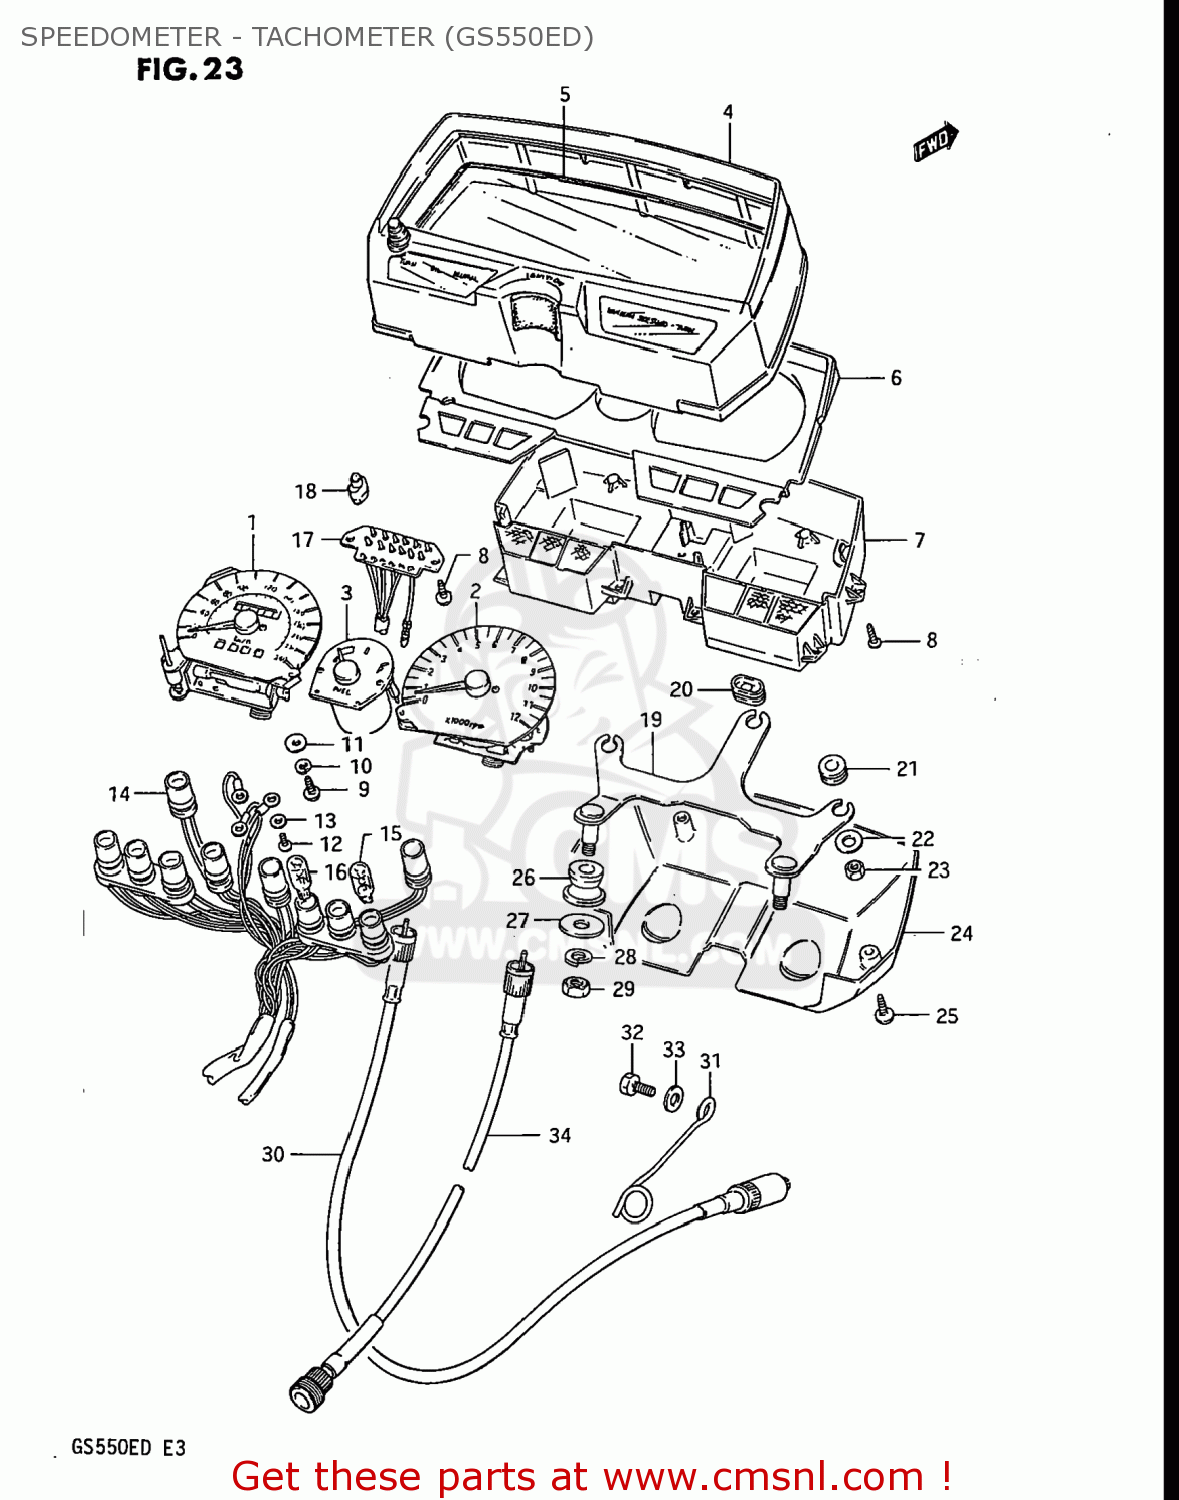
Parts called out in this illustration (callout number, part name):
1	SPEEDOMETER
2	TACHOMETER
3	METER,FUEL
4	HOOD,METER
5	GLASS,SPEEDOMETER
6	PLATE,METER WINDOW
7	CASE,METER,INNER
8	SCREW,GEAR INDICATOR
9	SCREW
10	LOCK WASHER
11	WASHER
12	SCREW
13	WASHER
14	SOCKET
15	BULB(12V3.4W,T10,BF175-01450A)
16	BULB(12V1.7W,T10,WB121)
17	SOCKET,GEAR INDICATOR
18	BULB(14V1.12W)
19	BRACKET,METER
20	CUSHION,METER
21	CUSHION,METER
22	WASHER,METER
23	NUT
24	COVER,METER,UNDER
25	SCREW
26	CUSHION,METER BRACKET
27	WASHER (8.5X20X1.6)
28	LOCK WASHER
29	NUT
30	CABLE ASSEMBLY,SPEEDOMETER
31	CLAMP,SPEEDOMETER CABLE
32	BOLT, UPPER
33	WASHER
34	CABLE ASSY,TACHOMETER
